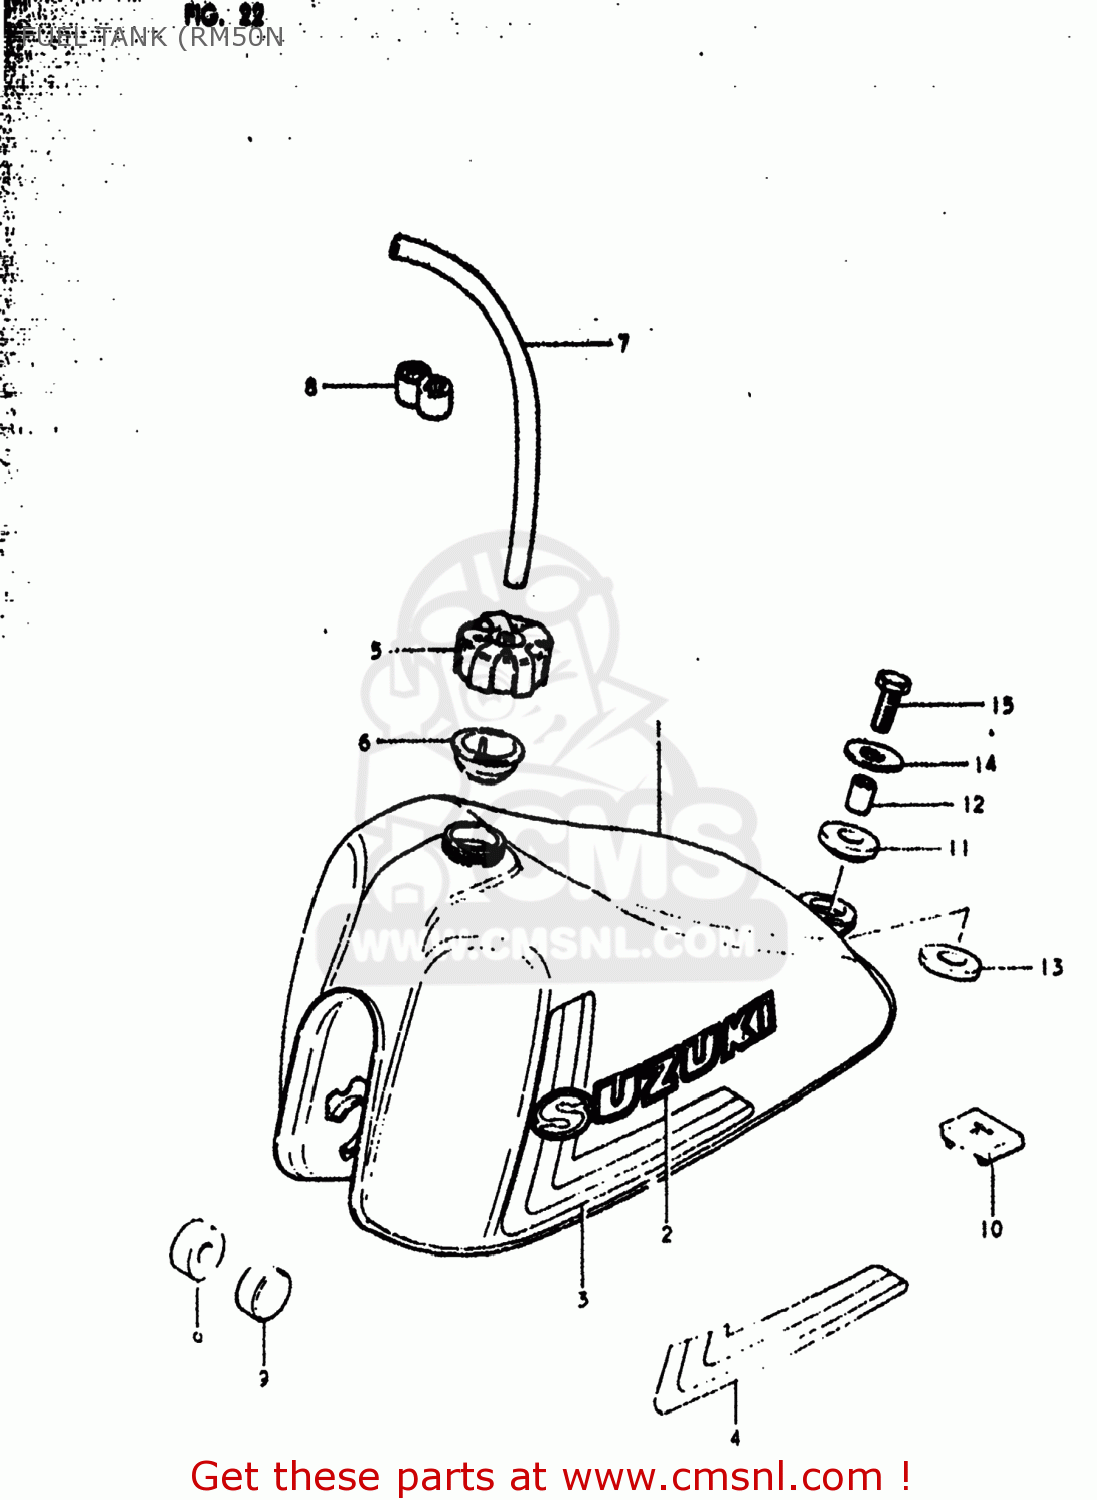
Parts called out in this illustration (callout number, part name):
1	TANK ASSEMBLY,FUEL
2	EMBLEM
3	TAPE SET
4	TAPE SET,FUEL TANK
5	CAP ASSEMBLY,FUEL TANK
6	GASKET,FUEL TANK CAP
7	HOSE
8	CLAMP,FUEL TANK BREATHER HOSE
9	CUSHION
10	CUSHION,FUEL TANK
11	CUSHION
12	SPACER (8.8X12X13.5)
13	CUSHION
14	BOLT
15	WASHER (8.5X29X1.6)
